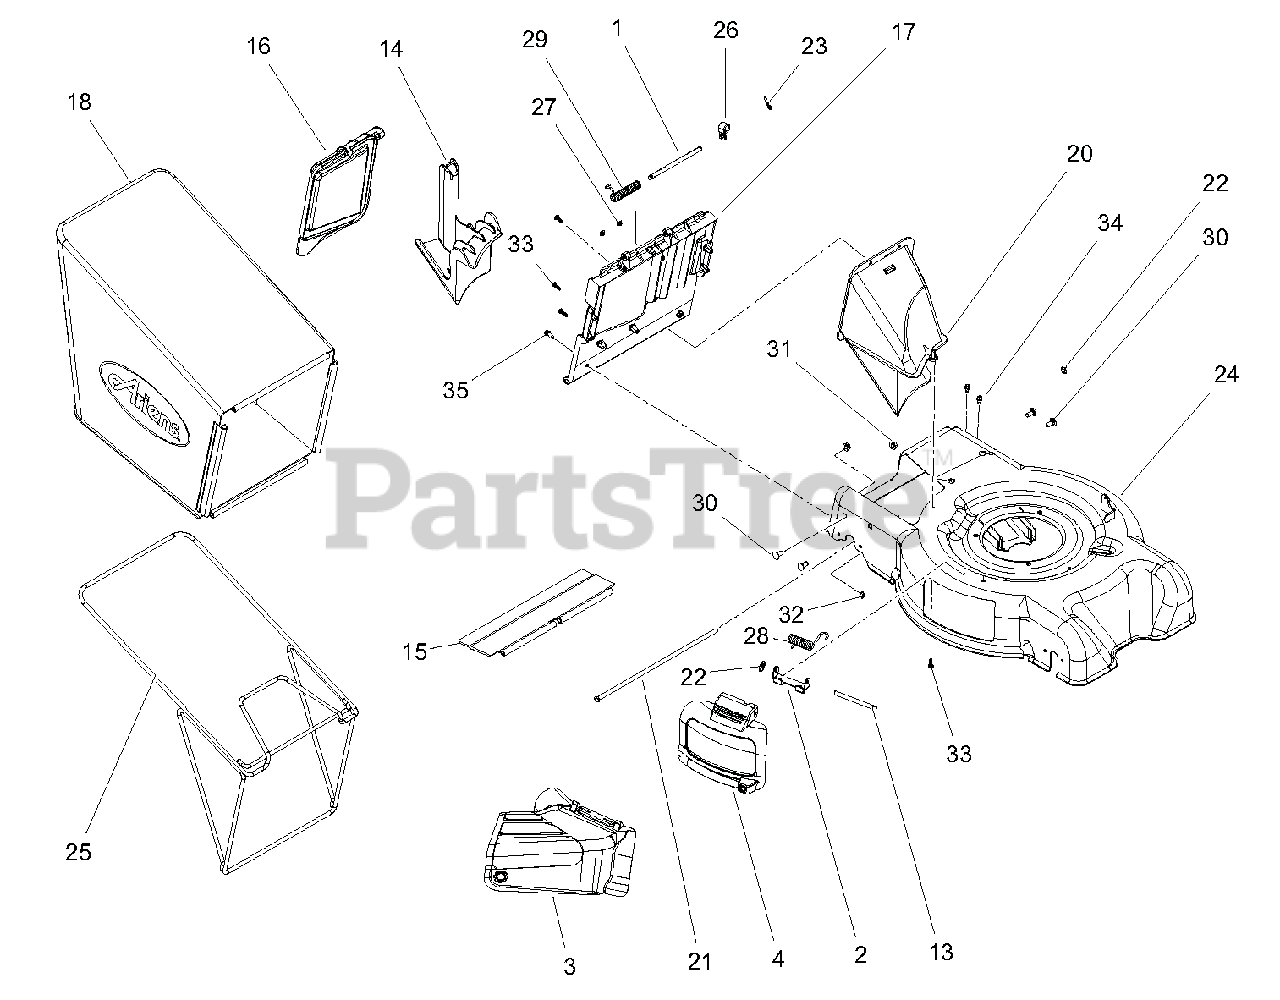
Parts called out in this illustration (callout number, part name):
1	PIN, 5/16 X 5.80"
2	BRKT, HINGE LM
3	CHUTE, SIDE DISCHARGE - LM
4	COVER, SIDE DISCHARGE - LM
13	PIN, HINGE
14	PLUG, MULCH
15	GUARD, REAR
16	REAR DOOR W/ SAFETY DECAL
17	HANGER, BAG
18	BAGGER, ARIENS LM
20	CHUTE, REAR DISCHARGE LM
21	ROD, REAR GUARD
22	NUT-PUSH .312
23	PIN-HAIR INT .08X.18X1.18 YWZC
24	DECK W/ SAFETY DECAL
25	FRAME, BAG
26	CLAMP, LM CABLE
27	PLUG,5/16 HOLE,.125 MATL PLSTC
28	SPRING, DOOR HINGE
29	SG-TORS .120X.68X3.09
30	@BLT-RDHDSQNK .31-18X.75 G5YZ
31	@NUT-LK-TOP-FLG .31-18 YWZC
32	@NUT-LK-TOP-FLG .25-20 YWZC
33	SCR-TAP 12-14X.75PLSTITE @BLZC
34	@SCR-TAP .25-20X.37 HWH YWZ TR
35	@SCR-TAP .25-20X.62 HWH TR YWZ
